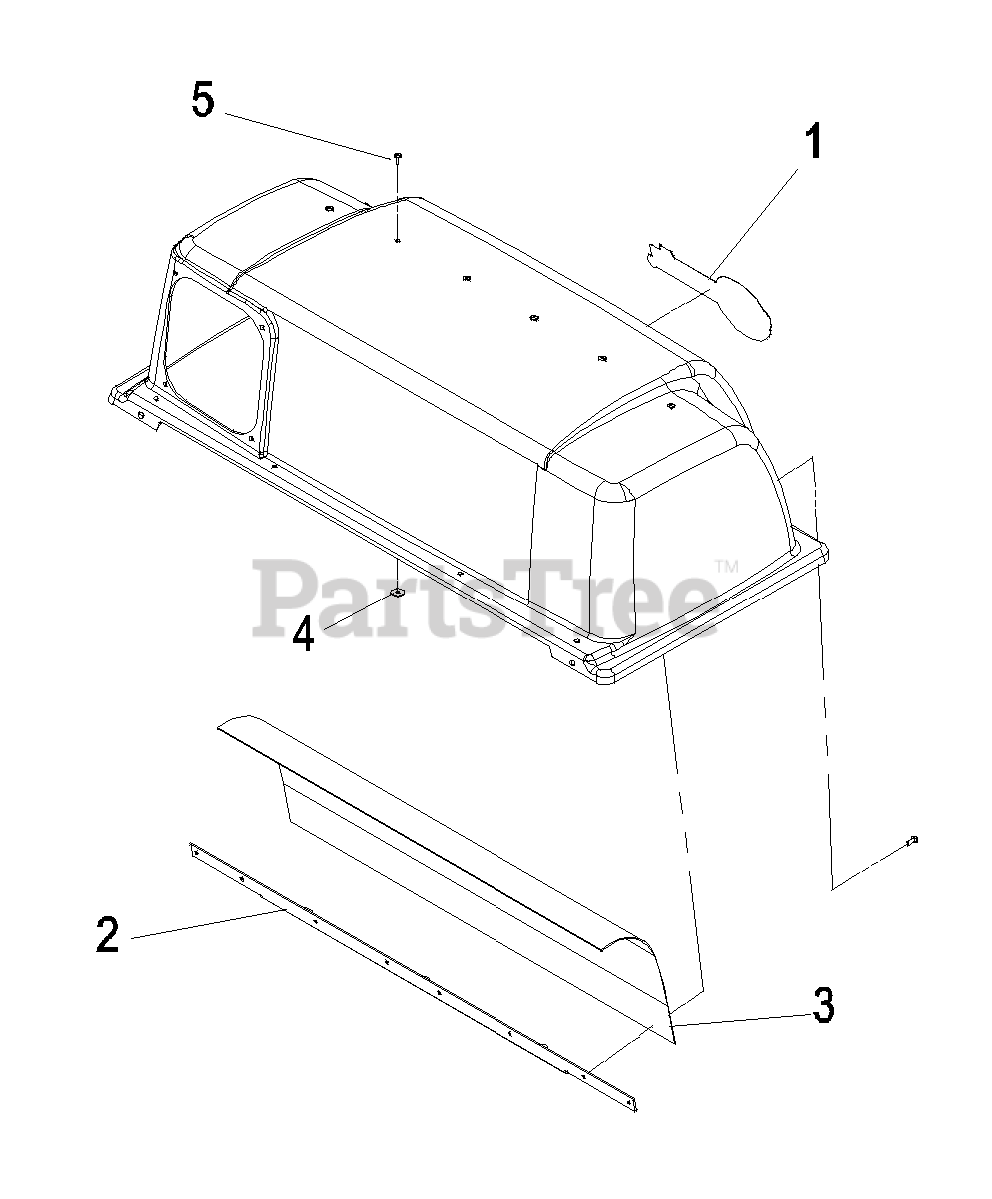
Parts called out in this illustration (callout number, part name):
1	DECAL, EXMARK LOGO
2	SUPPORT-SCREEN
3	SCREEN-BAGGER
4	WASHER-FLAT
5	RIVET-BLIND
